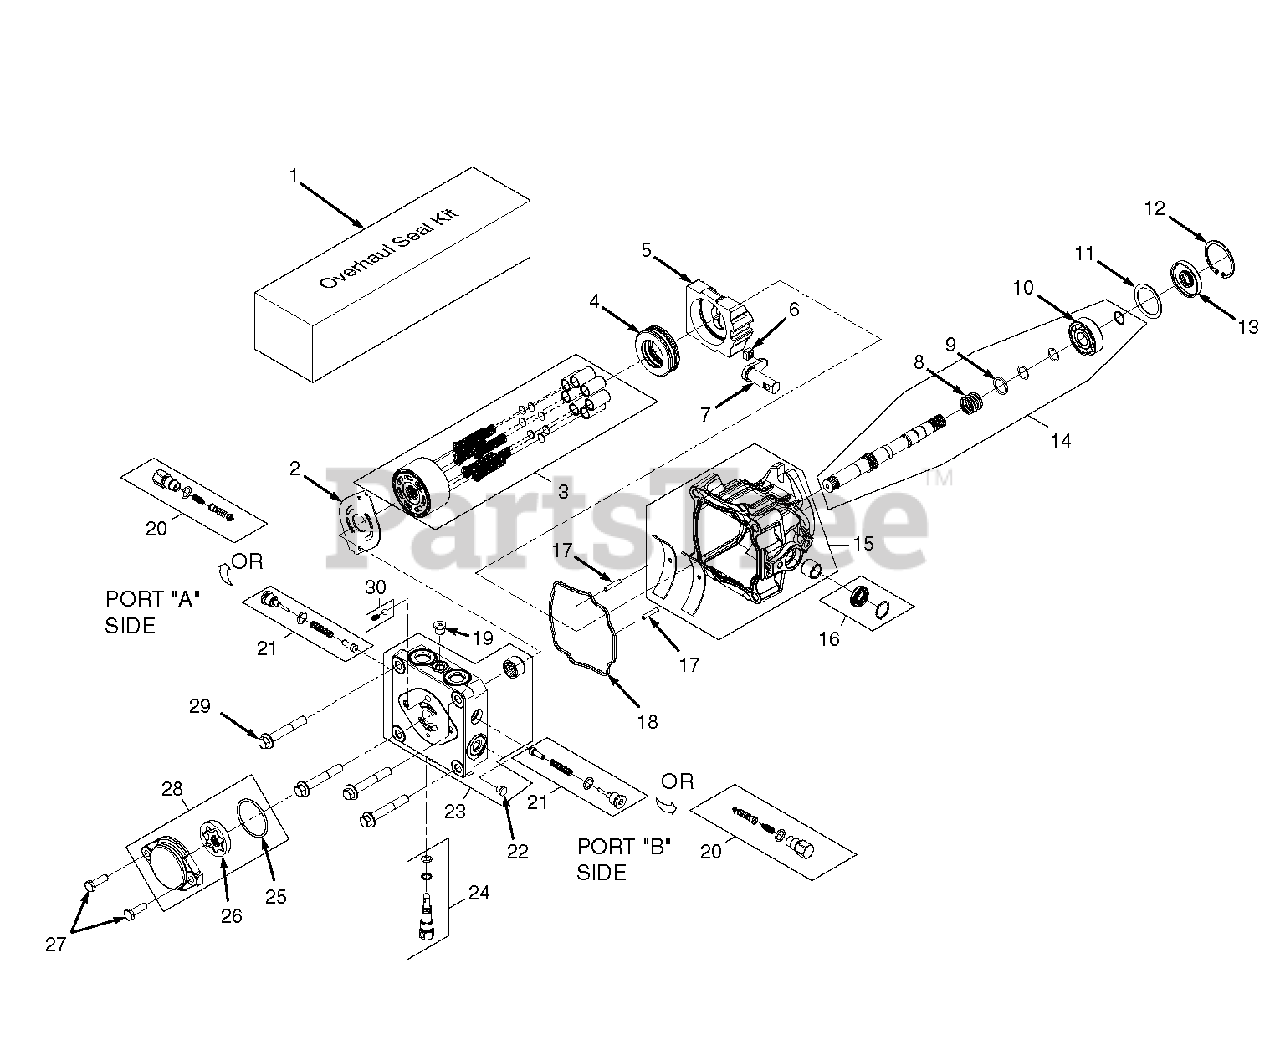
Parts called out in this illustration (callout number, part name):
1	Overhaul Seal Kit
2	Valve Plate
3	Cylinder Block Kit - 16cc
4	Thrust Ball Bearing Assembly
5	Variable Swashplate
6	Slot Guide
7	Trunnion Arm
8	Block Spring
9	Block Thrust Washer
10	Shaft Ball Bearing
12	Retaining Ring
14	Kit, Pump Shaft
15	Housing Kit
16	Trunnion Seal Kit
18	O-Ring
19	Straight Thread Plug
20	Shock Valve Kit (.031 Orifice)
21	Shock Valve Kit (.024 Orifice)
22	Straight Thread Plug
23	End Cap Kit
24	Bypass Valve Kit
26	Gerotor Assembly (.19 cu.in./rev.)
27	Socket Head Cap Screw (M8 x 1.25-25mm)
28	Charge Pump Kit (.19 STD. Splined)
29	Hex Screw, Flanged Head (M10 x 1.50-65mm)
30	Charge Relief Kit
